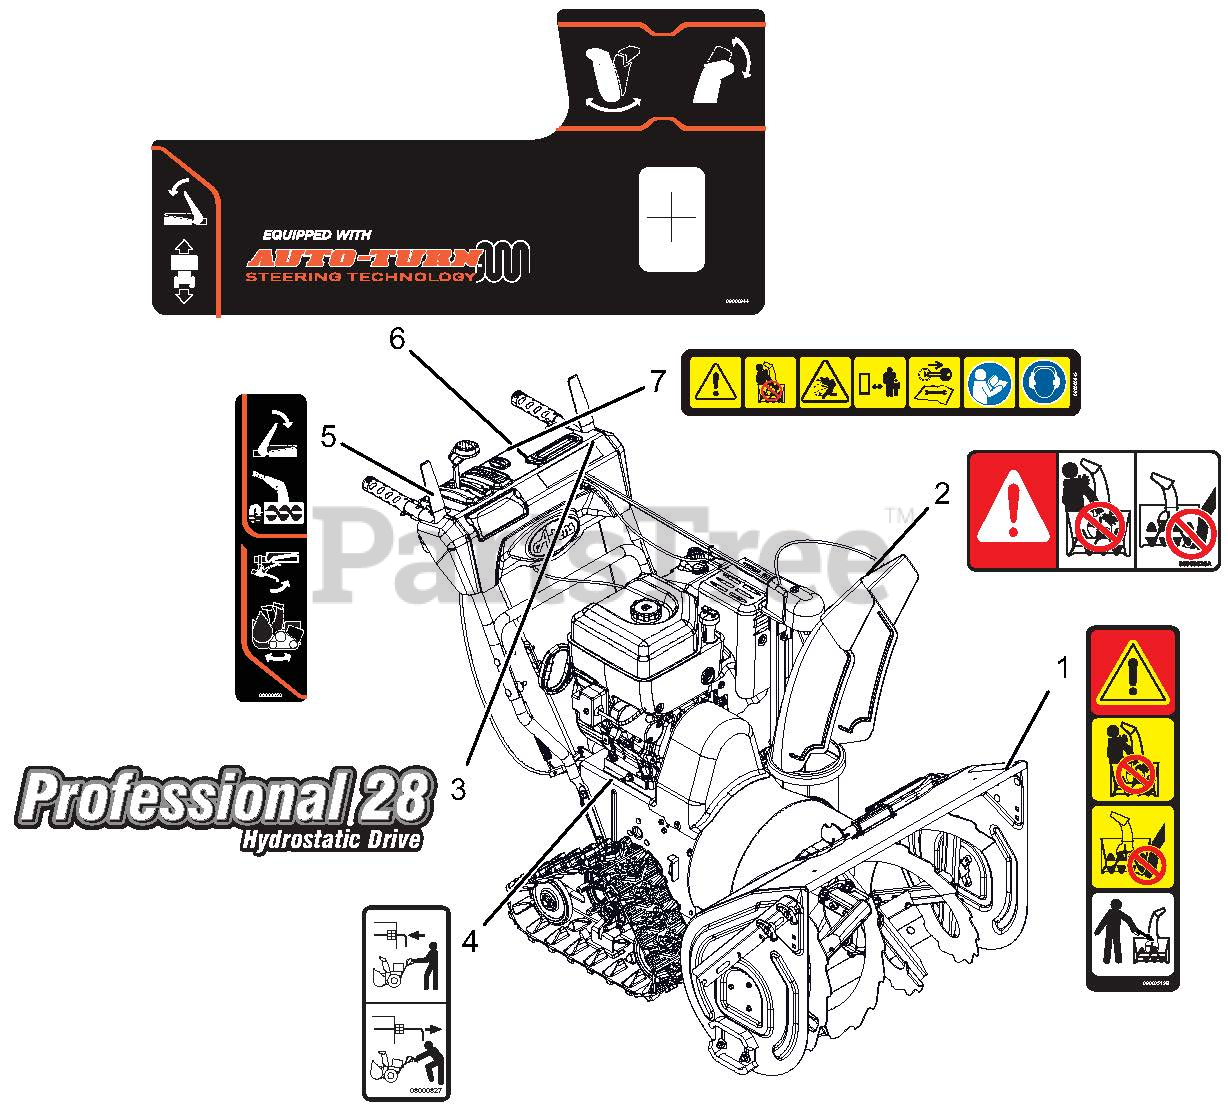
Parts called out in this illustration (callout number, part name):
1	DECAL, DANGER - ROTATING PARTS
2	DECAL, DANGER
3	DECAL, PRO HYDRO 28 DASH
4	DECAL, BYPASS
5	DECAL,CONTROL-RH TRACK
6	DECAL,CONTROL-LG QT2
7	DECAL,DASH - SAFETY
